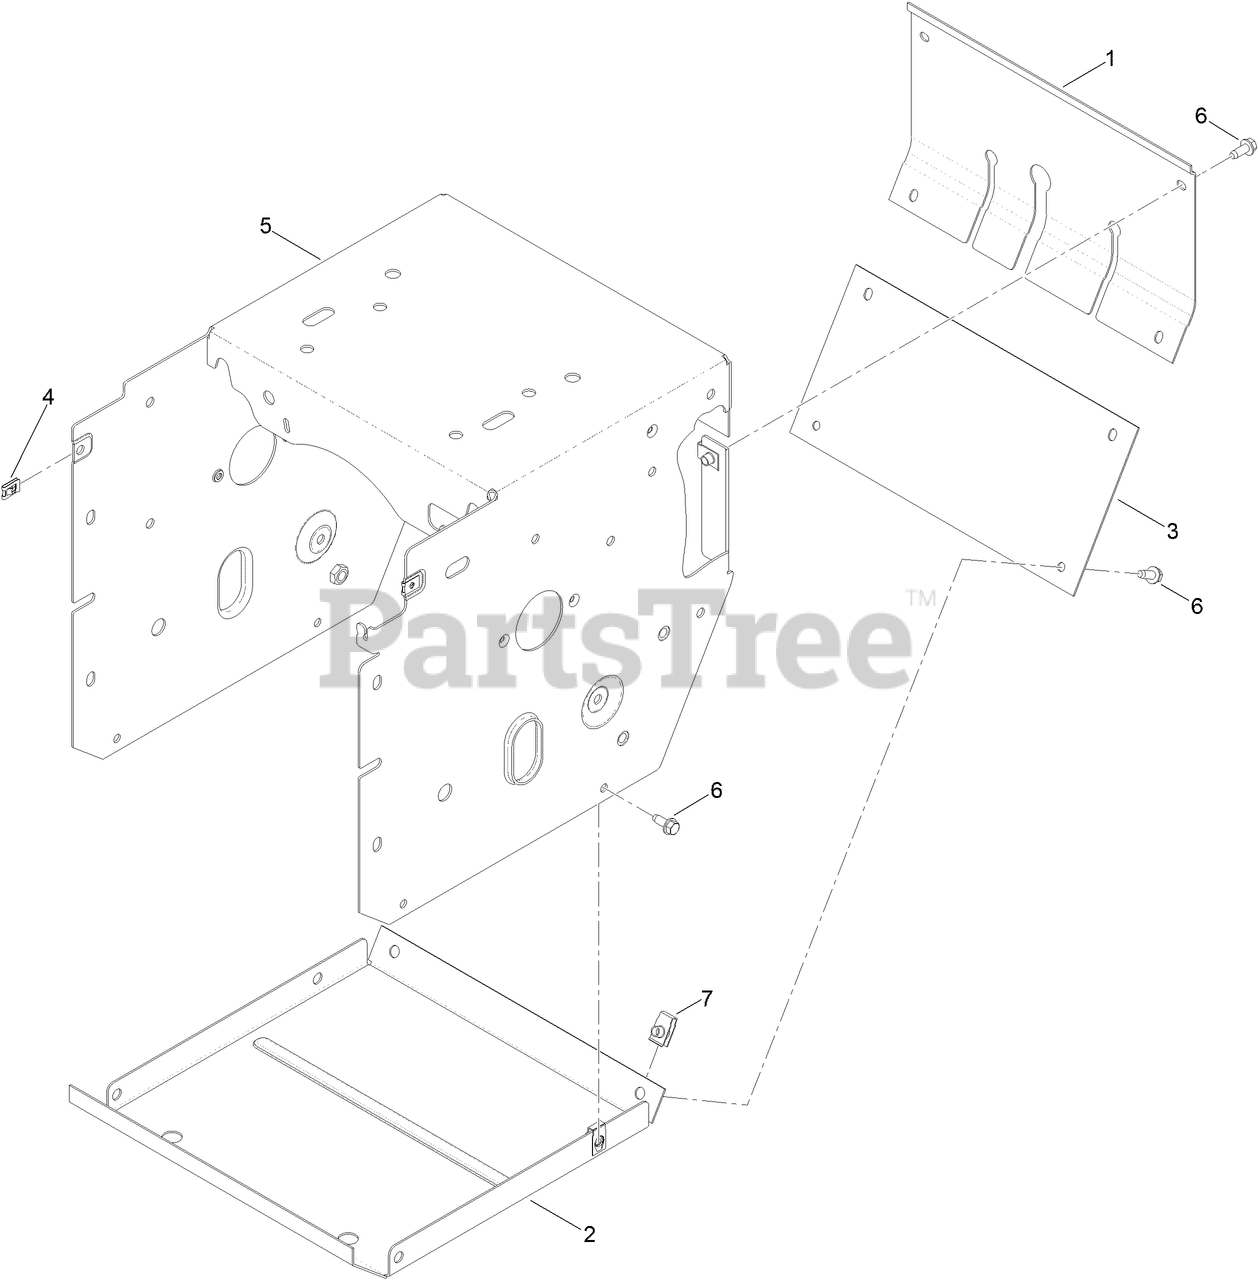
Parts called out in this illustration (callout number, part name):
1	COVER-UPPER
2	PAN-BOTTOM
3	COVER-LOWER
4	NUT-SPEED, U-TYPE
5	FRAME-TRACTION
6	SCREW-HWH
